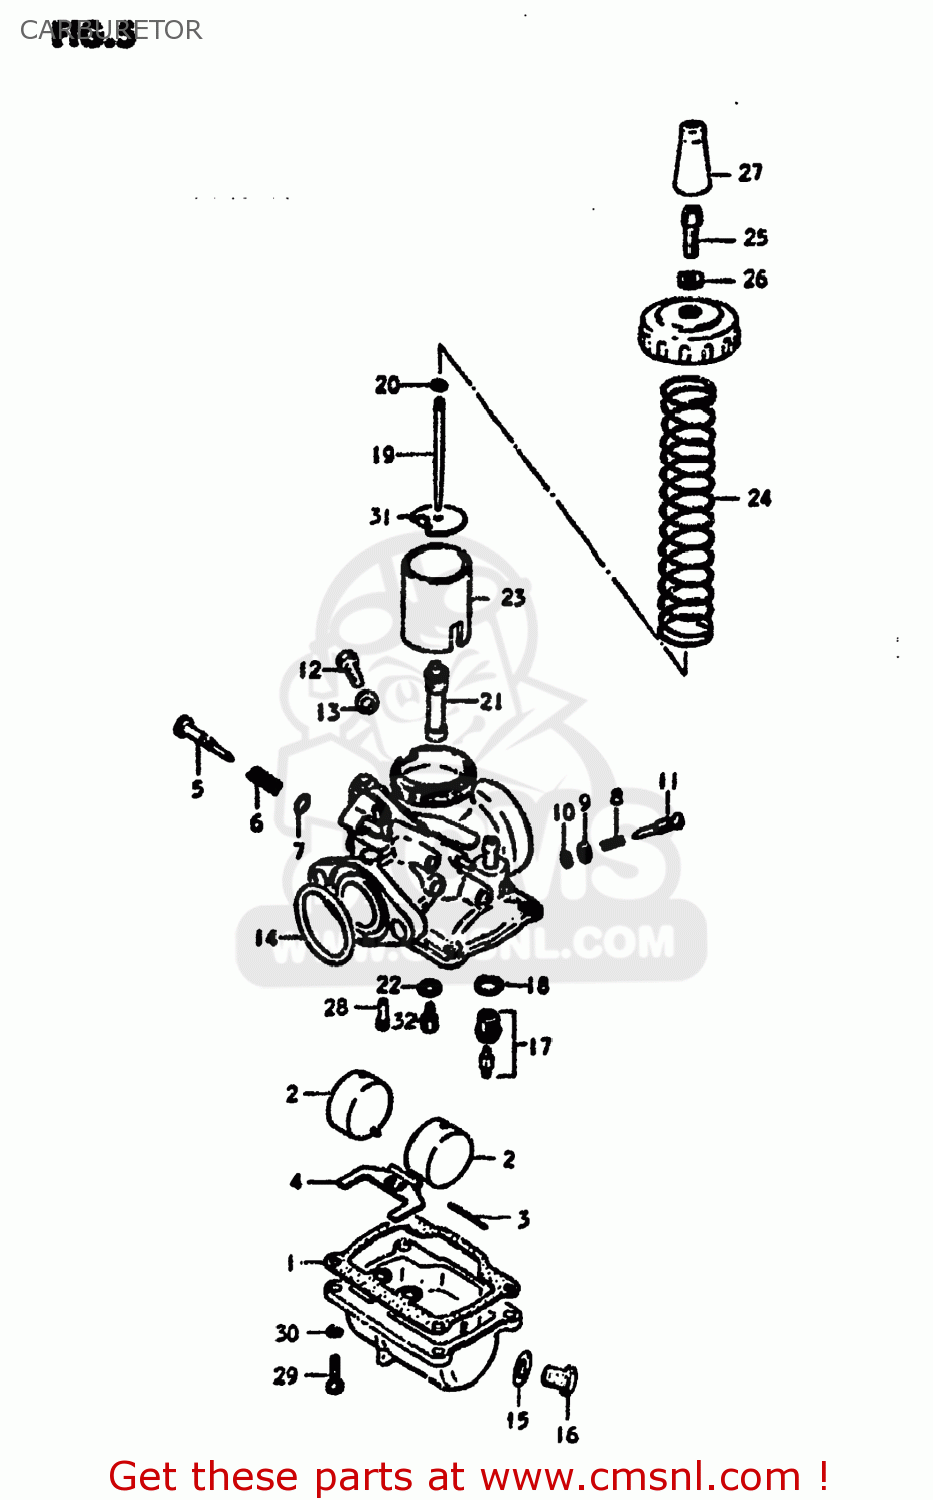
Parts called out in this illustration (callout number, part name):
1	GASKET,FLOAT CHAMBER (NAS)
2	FLOAT
3	PIN,FLOAT
4	PLATE
5	SCREW,THROTTLE STOP
6	SPRING,PILOT
7	O-RING
8	SPRING
9	WASHER,PILOT AIR SCREW
10	O RING
11	SCREW,PILOT AIR
12	BOLT
13	GASKET,THRO VALVE INSPECTION (NAS)
14	O RING
15	GASKET,DRAIN,PLUG (NAS)
16	PLUG
17	VALVE ASSEMBLY,NEEDLE
18	GASKET,VALVE SEAT (NAS)
19	NEEDLE,JET
20	CLIP
21	JET,NEEDLE
22	WASHER
23	VALVE,THROTTLE
24	SPRING, THROTTLE VALVE
25	ADJUSTER,CABLE
26	NUT
27	CAP
28	JET
29	SCREW
30	LOCK WASHER
31	SEAT,THROTTLE VALVE SPRING
32	JET,MAIN 85
